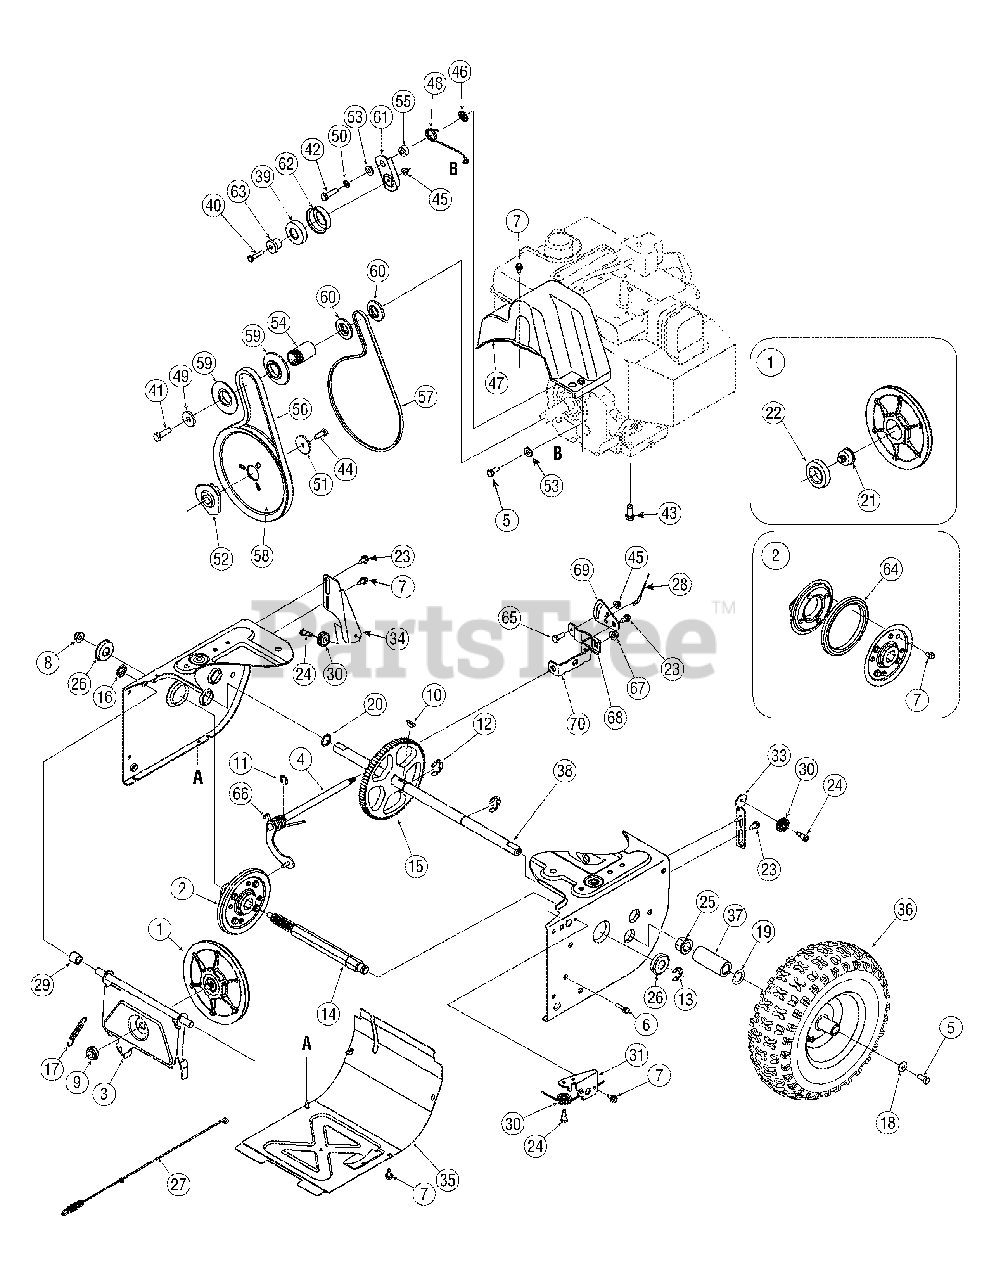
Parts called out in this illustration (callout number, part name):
1	Disc Assembly, Friction Wheel
2	Friction Wheel Assembly, 5.5 OD
3	Support Bracket, Friction Wheel
4	Shift Assembly, Rod
5	Hex Screw, 5/16-24, .750, Gr5
6	Screw, 1/4-20, 1.000
7	Screw, 1/4-14 x .625
8	Nut, Flange Lock, 3/8-16, Nylon
9	Nut, Jam Lock, 5/8-18, Gr5, Nylon
10	Key, Hi Pro, 3/16 x 3/4 Dia.
11	E-ring, .500 Dia.
12	E-ring, Retaining, .875 Dia.
13	E-ring, .750 Dia.
14	Hex Shaft, .8125, 7-Tooth
15	Gear, 80-Tooth
16	Speed Nut, .500
17	Extension Spring
18	Washer, Bell, .340 x .872 x .060
19	Washer, Flat, .793 x 1.24 x .060
20	Washer, Flat, .75 x 1.00 x .060
21	Pin, Friction Disc
22	Ball Bearing, 30 x 55 x 13
23	Screw, Shoulder, .37 x .105, 1/4-20
24	Screw, 1/4-28, .375
25	Bearing, Hex Flange x .75 ID
26	Bearing, Ball, 17 x 40 x 12
27	Clutch Cable, Wheel, 44.95"
28	Cable, Speed Selector
29	Spacer, .508 ID x .75 OD x .68
30	Roller, Cable
31	Front Guide Bracket, Auger Cable
33	Guide Bracket, Auger Cable
34	Guide Bracket, Drive Cable
36	Tires for Wheel Size 15 x 5
36	Valve
37	Spacer, 1.25 x .75 x 3.0
38	Axle, .75 x 22"
39	Ball Bearing
40	Hex Screw, 1/4-20, 1.25, Gr5
41	Hex Screw, 3/8-24, 1.25, Gr8
42	Hex Screw, 5/16-24, 1.25, Gr5
43	Screw, Sems, 3/8-16, 1.00
44	Hex Screw, 5/16-24, .875, Gr8
45	Nut, Flange Lock, 1/4-20, Nylon
46	Nut, Push-on, .25 Dia.
47	Cover, Belt
48	Spring, Torsion, .850 ID x .354
49	Washer, Flat, .406 x 1.25 x .157
50	Washer, Lock .3125
51	Washer, Flat, .34 x 1.50 x .150
52	Pulley, Adapter, .75 Dia.
53	Spacer, Shoulder, .317 x .50 x .102
54	Spacer, .875 ID x 1.185 OD
55	Spacer, .340 x .750 x .360
56	Belt, Auger Drive
57	Belt, Wheel Drive
58	Pulley, Auger Drive, 8.1 x .5
59	Pulley, Half, V x 2.600 OD
60	Pulley, Half, 1/4-V x 1.5 OD
61	Idler Bracket, Wheel Drive
62	Sleeve, Bearing Idler
63	Spacer, Shoulder, .26 x .79 x .538
64	Rubber, Friction Wheel, 5.5 OD
65	Hex Screw, 1/4-20, .620, Gr5
66	Spring, Torsion, .750 ID x .968
67	Nut, Flange Lock, 5/16-18, Nylon
68	Bracket, Shift Spacer
69	Pivot Bracket, Speed Selector
70	Shift Bracket, Speed Selector
